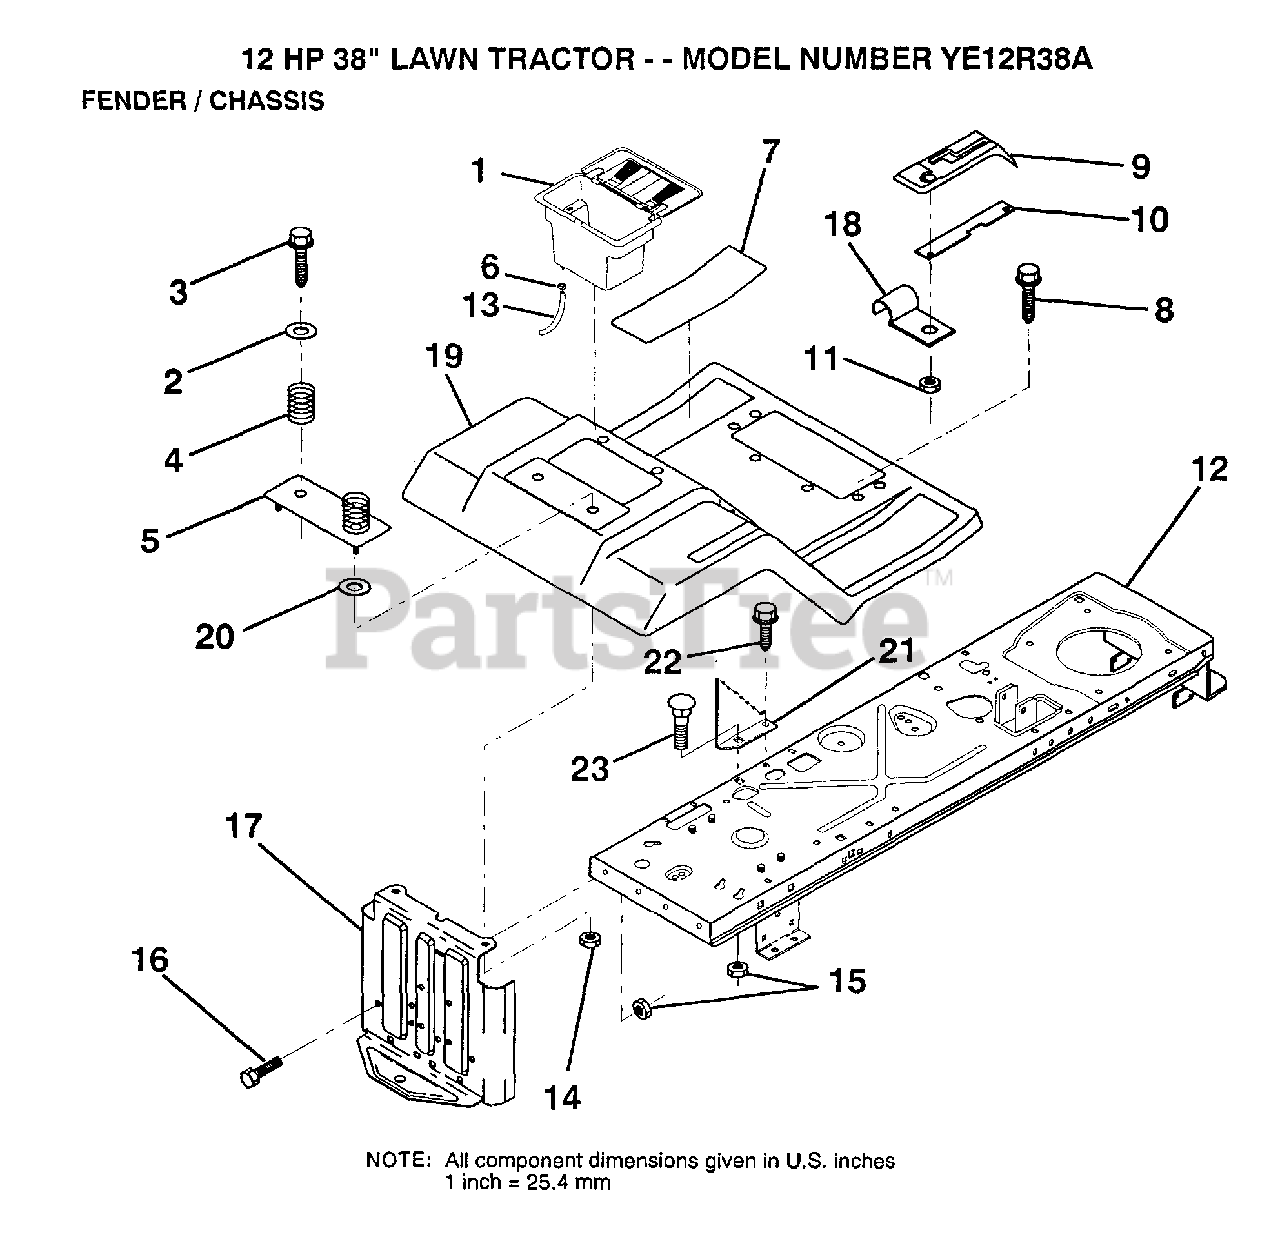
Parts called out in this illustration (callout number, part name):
2	WASHER
3	SCREW
4	SPRING COMPRESSIO
5	BTRY FENDER PLATE
6	HOSE CLAMP T
7	PAD FOOTREST
8	SCREW
10	"SHIFT LOCK, BAR"
11	NUT
14	NUT
16	BOLT
17	DRAWBAR
18	"CLIP,INSULATOR"
22	SCREW LT
